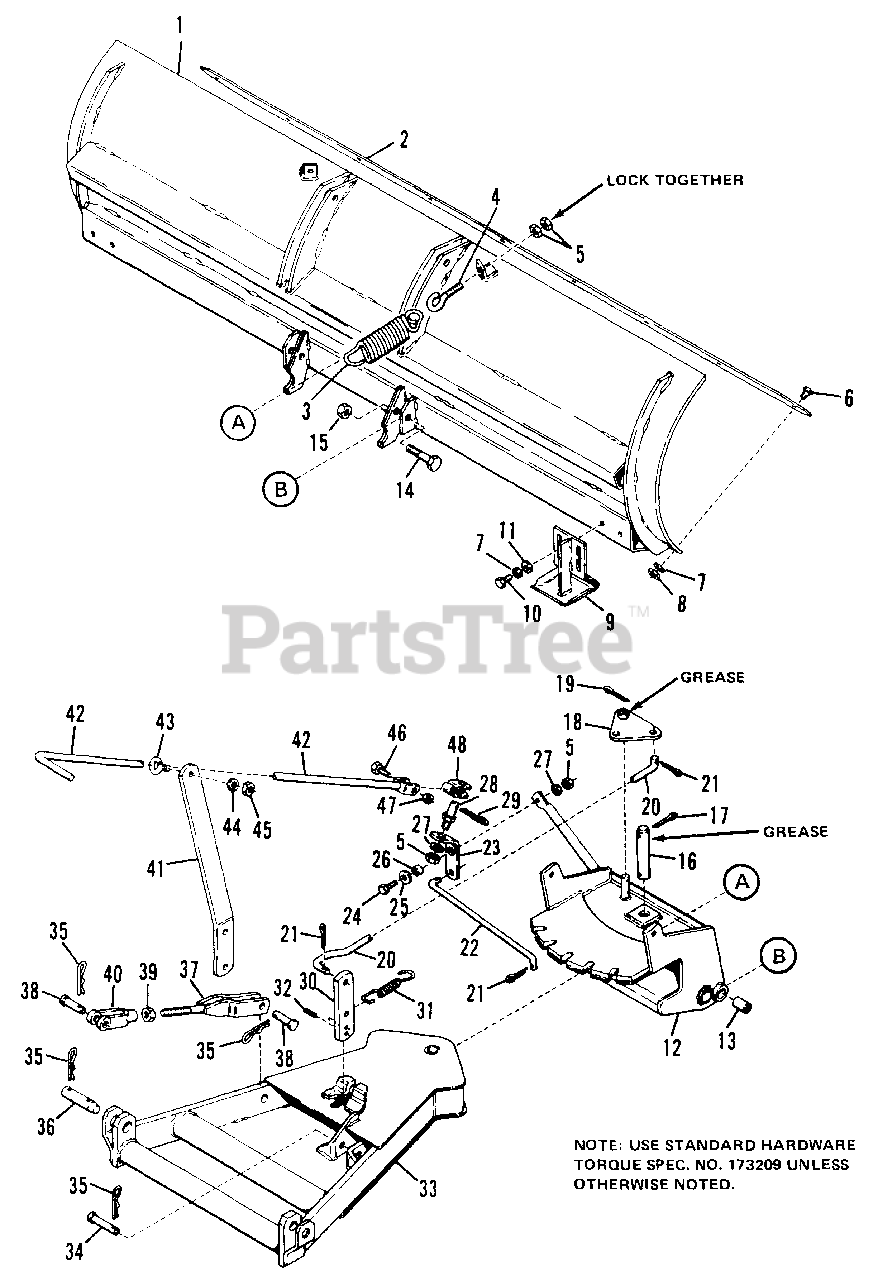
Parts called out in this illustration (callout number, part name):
1	BLADE ASSY, 60"
2	PLATE, Wear
3	SPRING, Tension
5	NUT, Hex, 5/16-18
6	BOLT, Rd. Hd., Sq. Nk., 3/8-16 x 1
7	LOCKWASHER, Spring, 3/8
8	NUT, Hex, 3/8-16
9	SHOE ASSY
10	CAPSCREW, Hex Hd., 3/8-16 x 3/4
11	WASHER, Plain, 3/8
12	FRAME ASSY, Pivot
14	CAPSCREW, Hex Hd., 1/2-13 x 2-1/4, Gr. 8
15	NUT, Hex, Lock, 1/2-13
16	PIN, Pivot
17	PIN, Cotter, 3/16 x 1-1/4
18	PLATE ASSY, Pivot
19	PIN, Cotter
20	ROD, Latch
21	PIN, Cotter, 3/32 x 5/8
22	ROD, Pivot
23	ARM, Pivot
24	CAPSCREW, Hex Hd., 5/16-18 x 1
25	WASHER, Plain, 5/16
27	LOCKWASHER, Spring, 5/16
28	STUD, Pivot
29	PIN, Quick, 1-7/8
32	PIN, Spring, 7/32 x 1
33	FRAME ASSY
35	CLIP, Spring
36	PIN, Hitch
38	PIN, End Adj.
39	NUT, Hex, Jam, 1/4-20
40	YOKE, End Adj.
42	HANDLE ASSY
44	LOCKWASHER, Spring, 1/4
45	NUT, Hex, 1/4-20
46	CAPSCREW, Hex Hd., 5/16-18 x 1-1/2
47	NUT, Hex, Lock, 5/16-18
